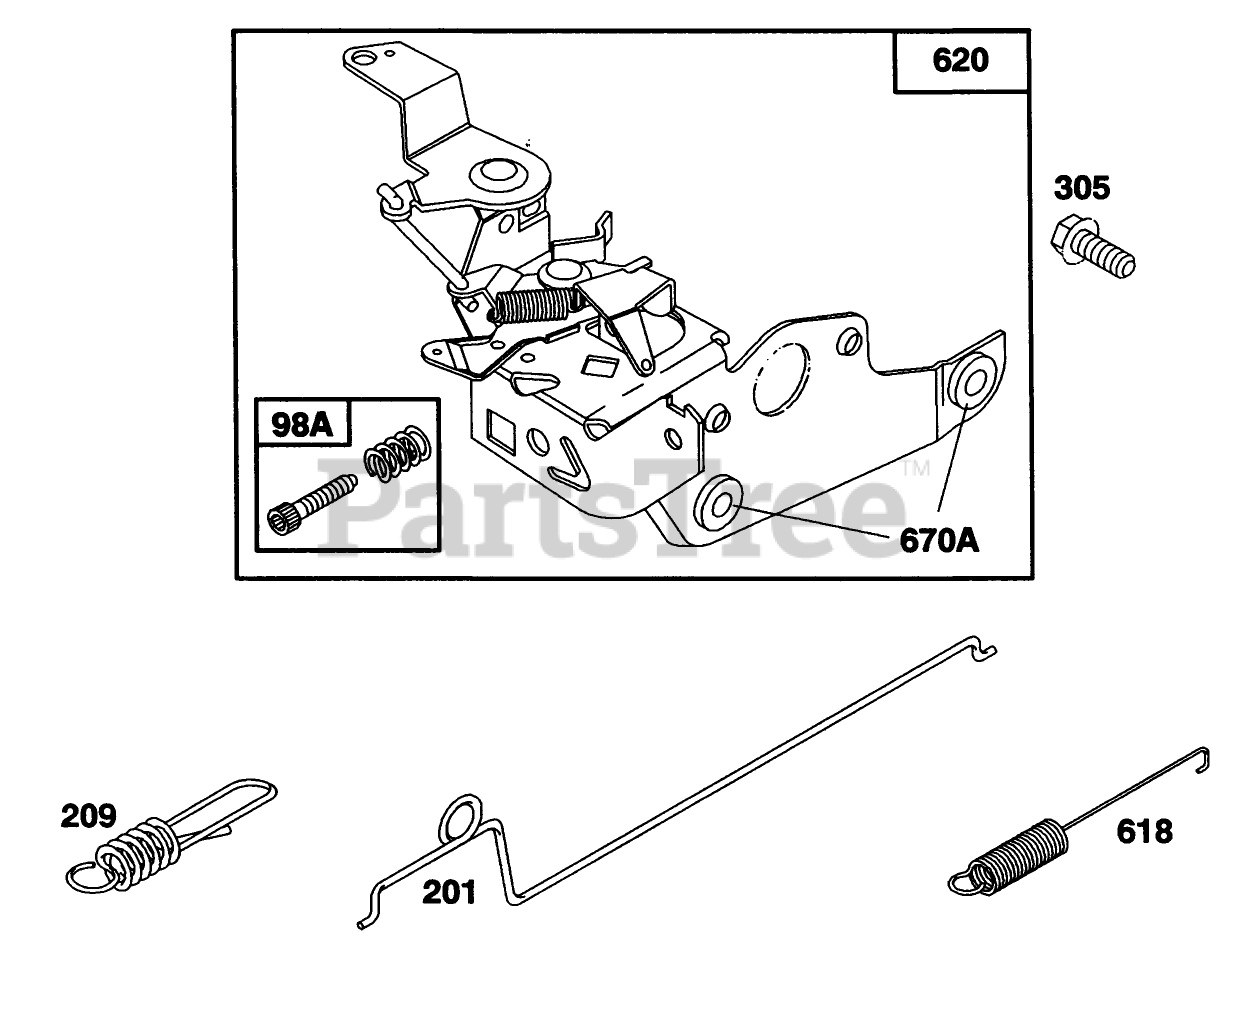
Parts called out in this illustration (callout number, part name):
98A	Screw Assy.
201	Link-Govemor
209	Spring-Govemor
305	Screw-Sem
618	Spring-Choke
620	Bracket Assembly
670A	Spacer
